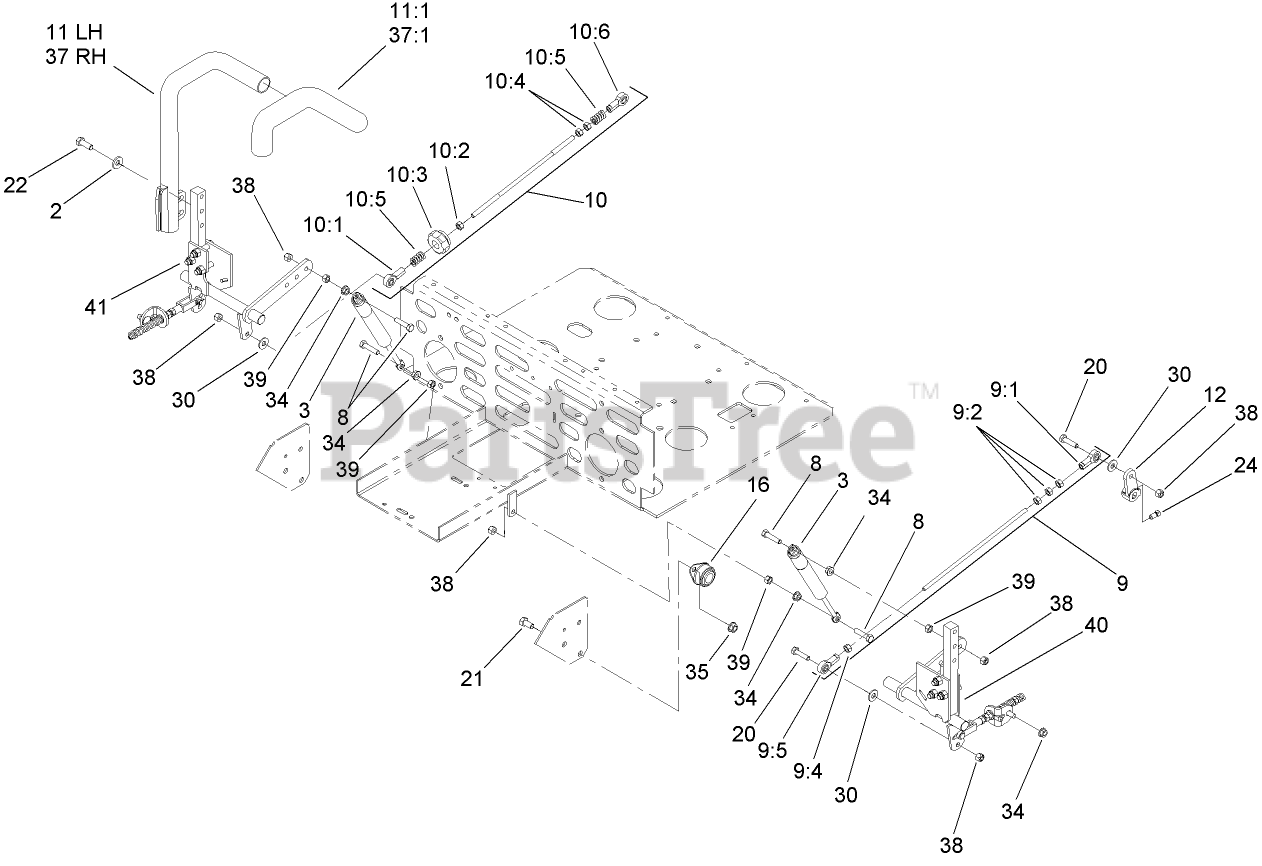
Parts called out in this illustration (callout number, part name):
2	WASHER-BELLEVILLE
3	DAMPER-CONTROL, MOTION
8	SCREW-HH
9	TRACKING ROD ASM
9:1	BALLJOINT-RH
9:2	NUT-HEX
9:5	BALLJOINT-LH
10	TRACKING ROD ASM
10:1	BALLJOINT-RH
10:2	NUT-HEX
10:3	KNOB-TRACKING
10:5	SPRING-COMPRESSION
10:6	BALLJOINT-LH
11	LH LEVER ASM
11:1	GRIP-CONTROL, MOTION
12	ARM-CONTROL, PUMP
16	BEARING-FLANGE, SIDE
20	SCREW-HH
21	SCREW-HH
22	SCREW-HH
24	SCREW-SET
30	WASHER-FLAT
34	NUT-HF
35	NUT-HHF, WHIZ
37	RH LEVER ASM
37:1	GRIP-CONTROL, MOTION
38	NUT-LOCK, NI
39	NUT-HEX
40	LH MOTION CONTROL ASM
41	RH MOTION CONTROL ASM
